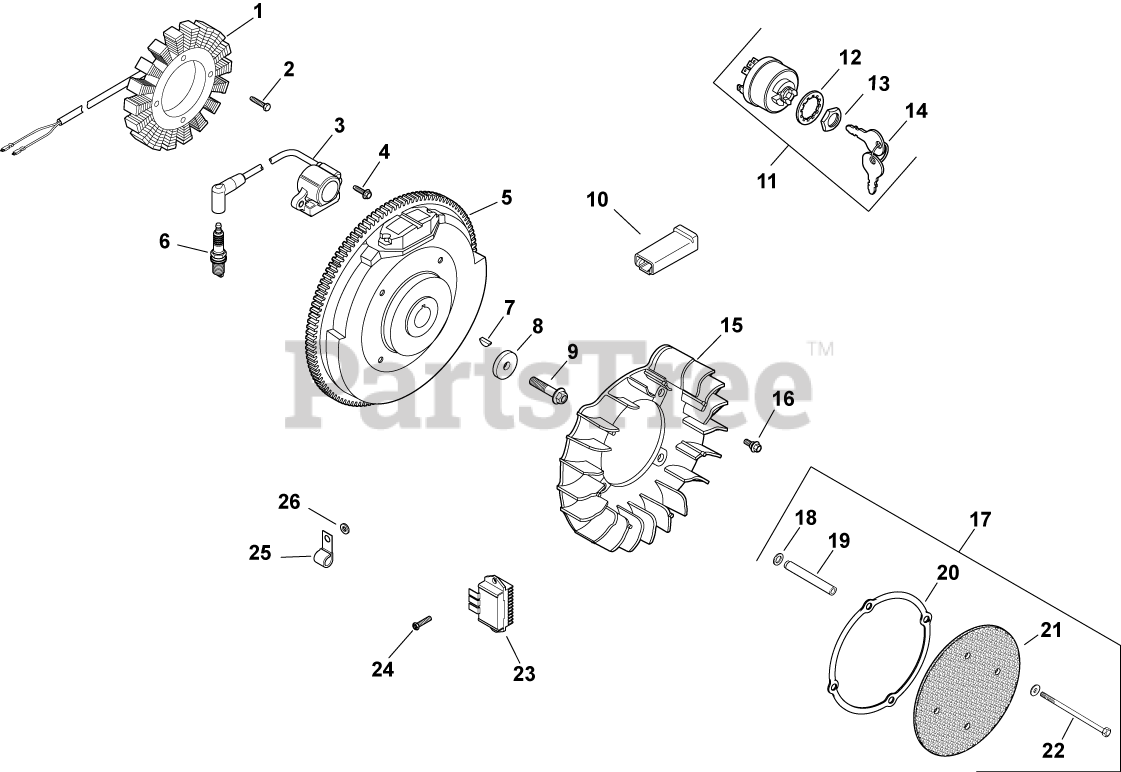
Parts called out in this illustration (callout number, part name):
1	KIT, 15 / 20 AMP STATOR
2	SCREW, M5X0.8X25 - (#25086402S)
3	KIT, MODULE IGNTN (CDI FIXED)
4	SCREW, FLG THD FRM M5X.8X20-(#25086399S)
6	PLUG, SPARK (STD)
7	KEY, 3/16" X 5/8"
8	WASHER, FLAT 13/32"
9	SCREW, FLG M10X1.5X85 USE 62 086 08-S
10	CONNECTOR (1 CONTACT)
11	SWITCH ASSY, KEY (KM)-USE 25 099 32-S
12	WASHER, INTERNAL TOOTH
13	NUT, KEY SWITCH
14	KEY, SET -USE 48 340 01-S
15	FAN USE 24 755 253-S
16	SCREW, SKT SET #10-24X1/4"
17	KIT, CHOPPER SCREEN
18	WASHER, SPRING 10 MM
20	RING, SUPPORT USE 25 141 08-S
21	SCREEN, GRASS-USE 24 162 39-S
22	SCREW, CAP M6X1.0X99.5
23	REG/RECT-15 AMP (KM)-USE 41 403 10-S
24	SCREW, HEX FLANGE HI-LO
25	CLIP, CABLE
26	WASHER, FLAT 1/4" (O.D. 1/2")
